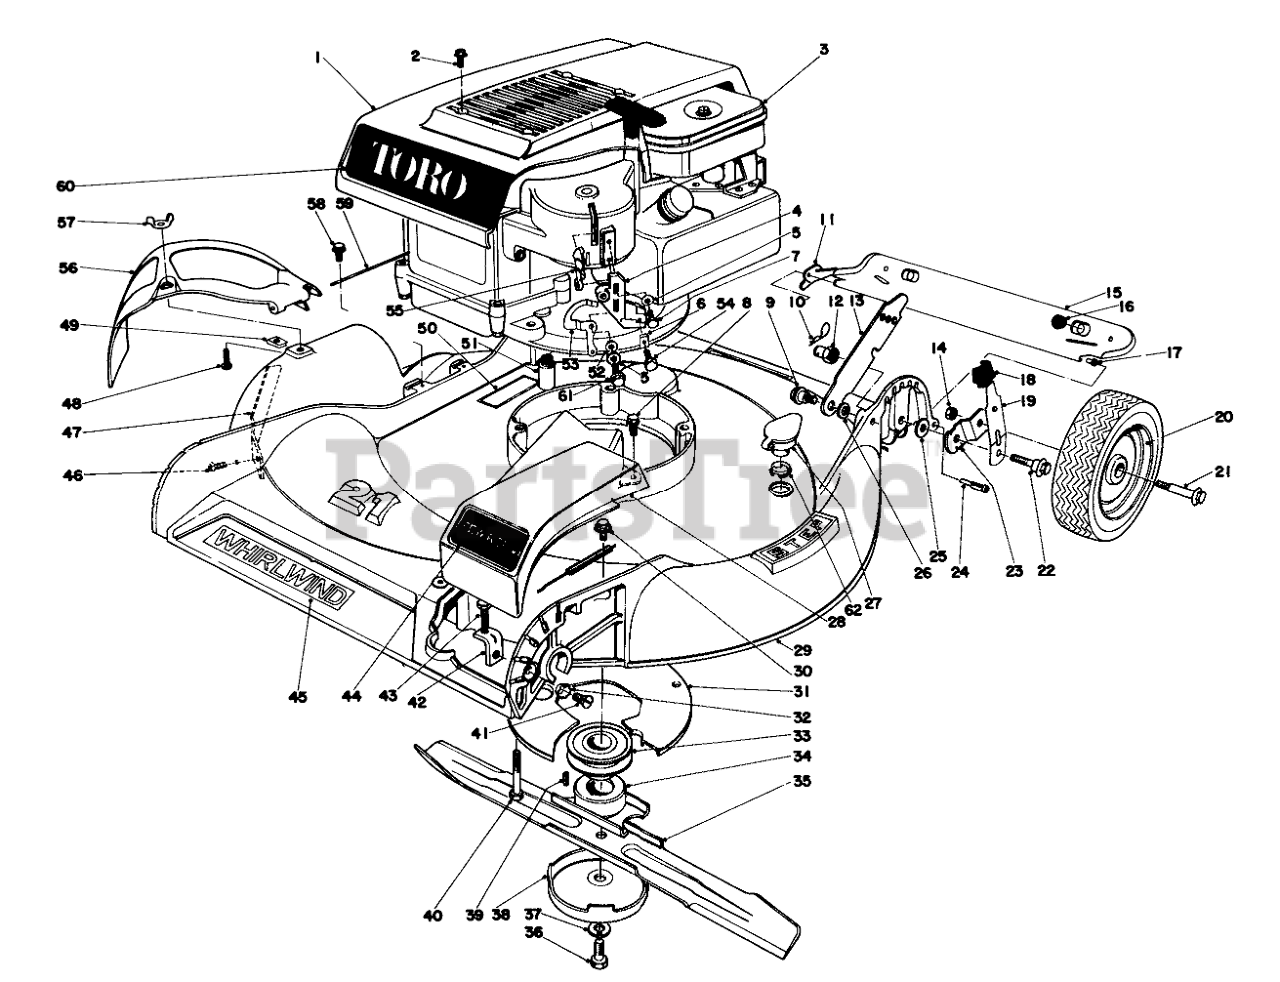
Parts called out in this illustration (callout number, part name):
1	Shroud
2	8X1/2 SELF TAP SCREW
3	Engine
4	Pivot Block
5	WASHER-FLAT
7	SCREW-SHWH
8	SCREW
9	SCREW-SHOULDER
10	PIN-COTTER, HAIR
11	Restraint R.H.
12	HANDLE PIVOT NUT
13	Latch
14	Nut
15	Rear Safety Shield (Incl. Ref. No. 16 & 17)
16	SKID BUTTON
17	SAFTEY SHIELD BUSHING
18	KNOB-ARM
19	SPRING ARM ASM
20	Wheel Assembly
22	PIVOT SCREW
23	PIVOT ARM PLATED
24	SAFTEY SHIELD SCREW
25	WASHER-PIVOT
26	SPACER
27	WASHOUT PLUG
28	Guard, Belt
29	Housing
30	SCREW-HWHTF
31	Grass Guard
32	Lockwasher
33	Pulley
34	Blade Retailer
35	Blade
36	SPECIAL SCREW
37	WASHER-LOCK
38	Anti Scalp Cup
39	Key Square
40	3/8-16 X 2-3/4 CAPSCR
42	Bracket-Gear Box
43	SCREW-HH
44	Decal Power Drive
45	Decal Toro
46	SCREW-HWH
47	Bar Safety
50	Decal
51	OIL DRAIN EXTENSION
52	BUSHING
53	CAM INTERLOCK
55	INTERLOCK LEVER
56	Deflector
57	NUT-WING SPECL
58	SCREW
59	HINGE PIN
60	Decal Whirlwind
61	SCREW-HHFTF
62	Washout Plug Adapter
